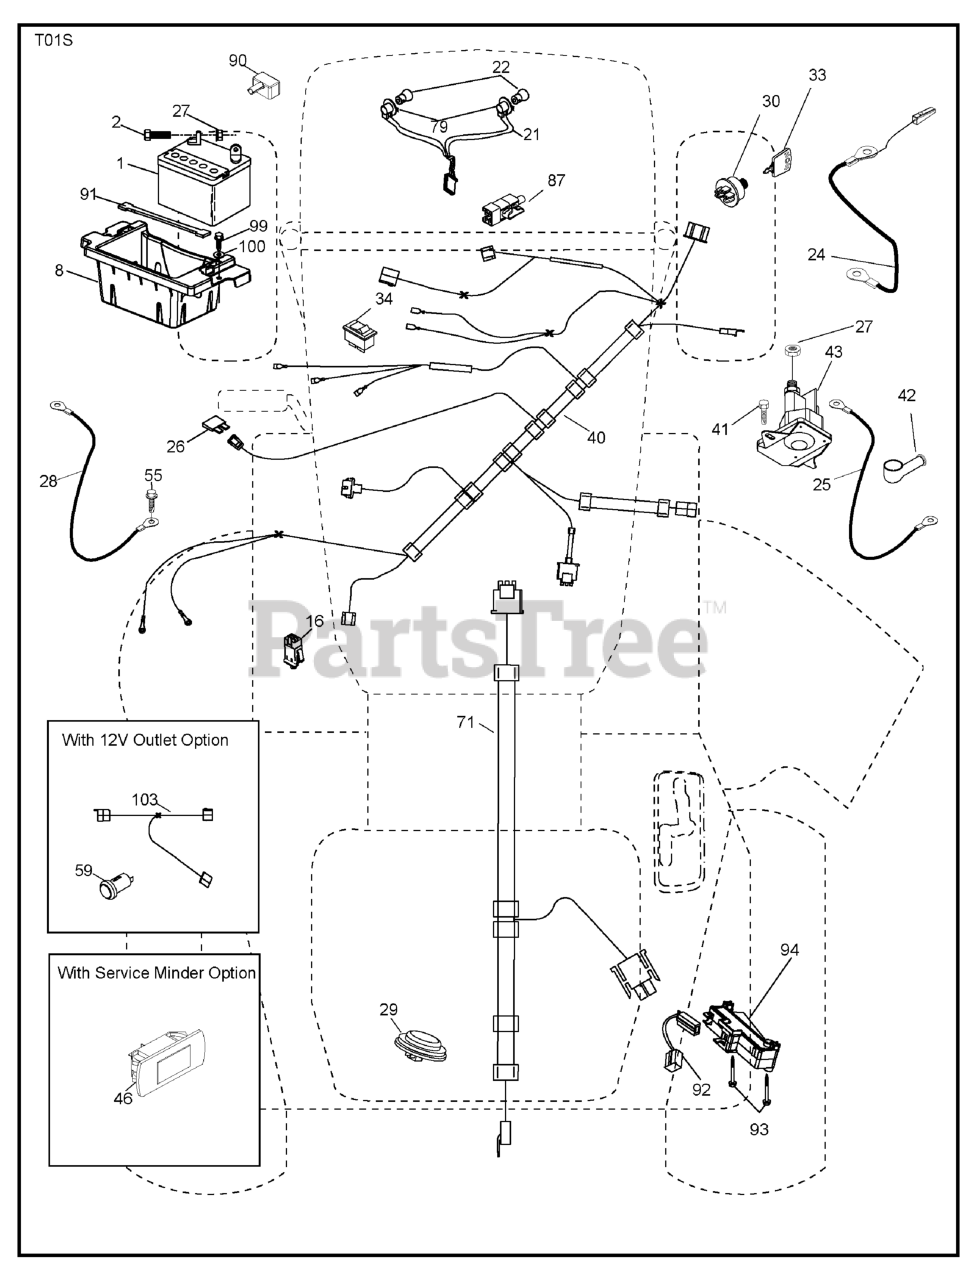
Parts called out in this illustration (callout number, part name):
1	Battery
2	Bolt Hex Hd 1/4-20 unc x 3/4
8	Box Battery
16	Switch Interlock
21	Harness Socket Light
22	Bulb, Light # 1156
24	Cable Btry
25	Cable Battery 6 Ga. Red 14.5
27	Nut Keps Hex 1/4-20 unc
28	Cable Ground
29	Switch Seat
30	Switch Ign
33	Key/Chain
34	Switch Light/Reset
40	Harness Ign
41	Screw 1/4-20 unc x 1/2
42	Cover Terminal Red
43	Solenoid
55	Screw 5/16-18 x 3/4
71	Harness Ign. Chass.
79	Socket Asm. Bulb
87	Switch Interlock Clutch Cable
90	Cover Terminal
91	Strap Battery
92	Harness Pigtail ROS
93	Screw Plastic 10-14 x 2.0
94	Modual Reverse ROS
99	Screw Hexwsh Thdrol 1/4-20 x 3/4
100	Washer 9/32 x 7/8 x 16 Ga.
